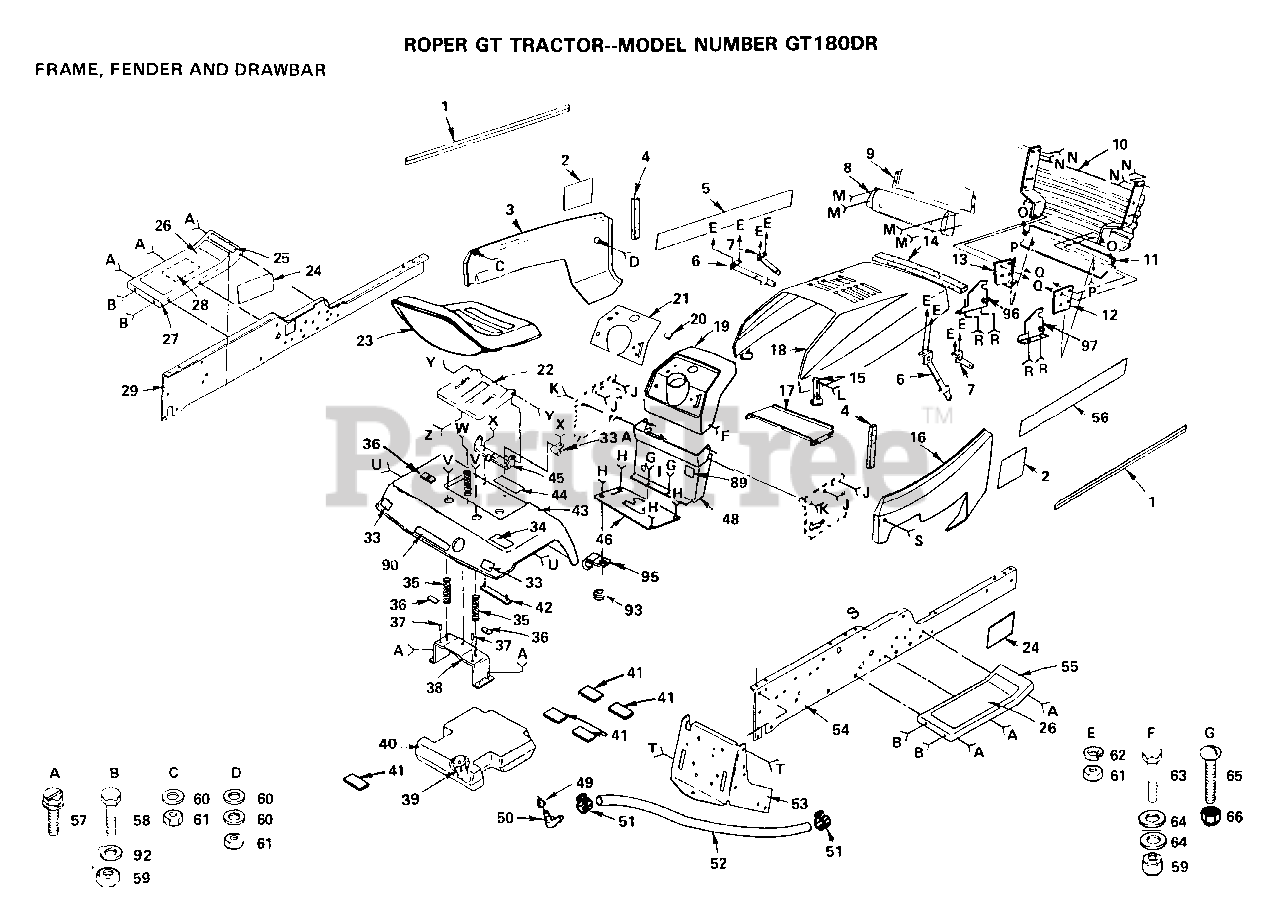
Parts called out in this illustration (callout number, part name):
4	FOAM STRIP HYT
9	LENS LT
12	SUPPORT RH YTH
13	SUPPORT LH YTH
14	FOAM-STRIP LT
20	PLUG-DASH T
21	DECAL-DASHBOARD
22	SEAT PAN T
25	DECAL T
27	FOOTREST LH YT
33	REFLECTOR-TAIL YT
34	DECAL-CAUTION
36	"CLAMP, SPRING LT"
37	NUT-PUSH YT
41	PAD-SPACER LT
45	BRACKET T
48	DASH ASSEMBLY
49	BUSHING OUTLET T
50	FUEL TANK STEM GT
57	SCREW
60	WASHER PM
63	BOLT
64	WASHER
65	SCREW
89	DECAL, INSTRUCTION
92	WASHER
93	GROMMET T
96	SUPPORT LH YTH
97	SUPPORT RH YTH
